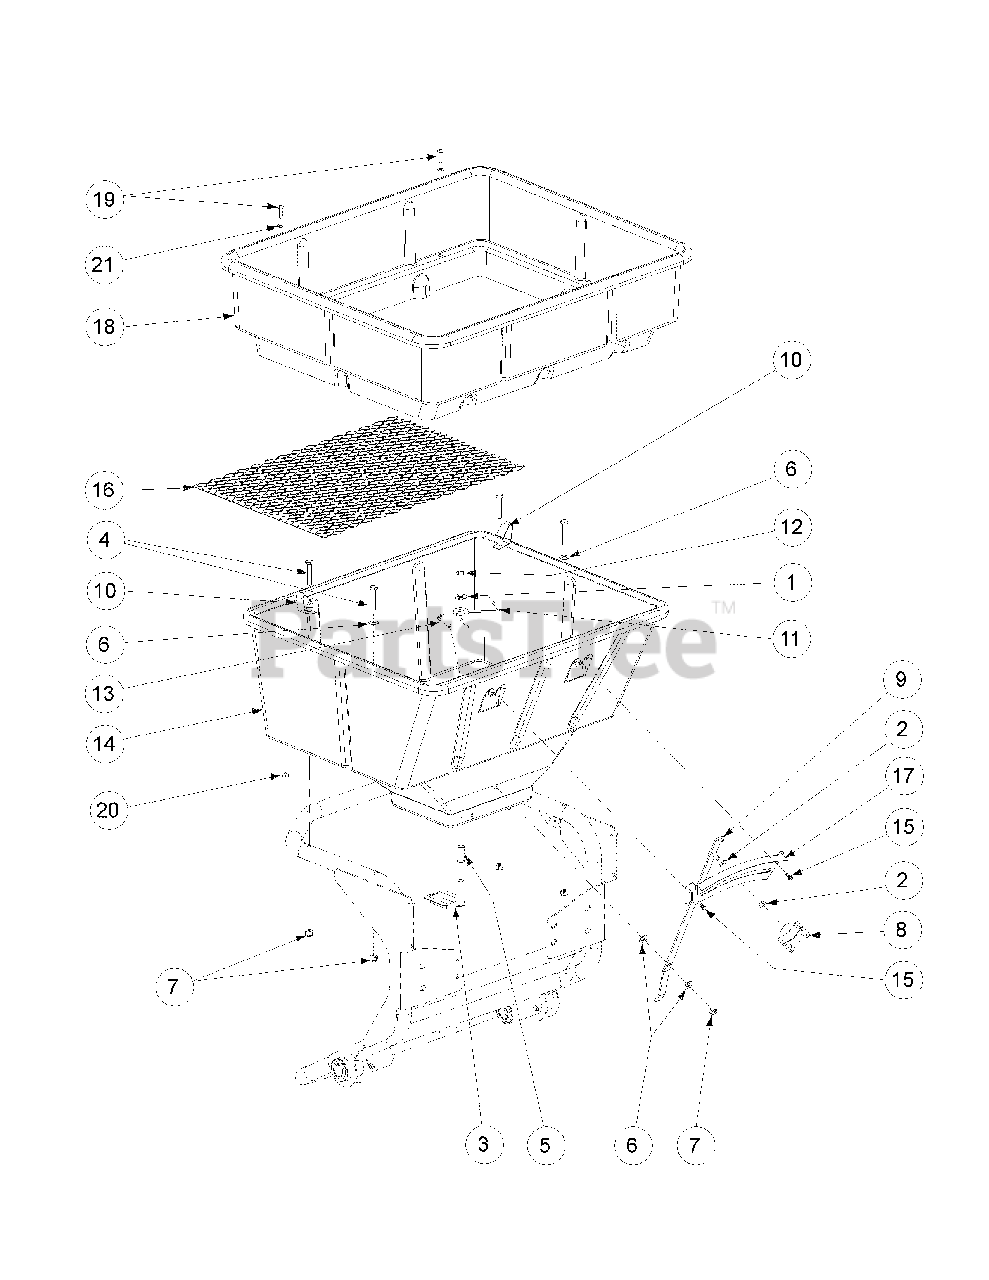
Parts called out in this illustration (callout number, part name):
1	Washer, 3/8
2	Washer, 1/4
3	Cam Agitator Assembly
4	Hex Cap Screw, 1/4-20 x 1.50
5	Agitator Bearing
6	Washer, 1/4, SS
7	Nut, 1/4-20, SS
8	Rate Control Knob
9	Rate Control Arm
10	Screen Clip, SS
11	Agitator Arm Assembly
12	Spring Retainer Clip
13	Machine Screw, 1/4-20 x 7/8
14	80# Hopper
15	Screw, #8 x 3/8, SS
16	Screen, SS
17	Rate Plate
18	Hopper Extension
19	Machine Screw, 10-24 x 3/4, SS
20	Nut, 10-24, SS
21	Washer, #8, SS
22	Decal, Front of Hopper
